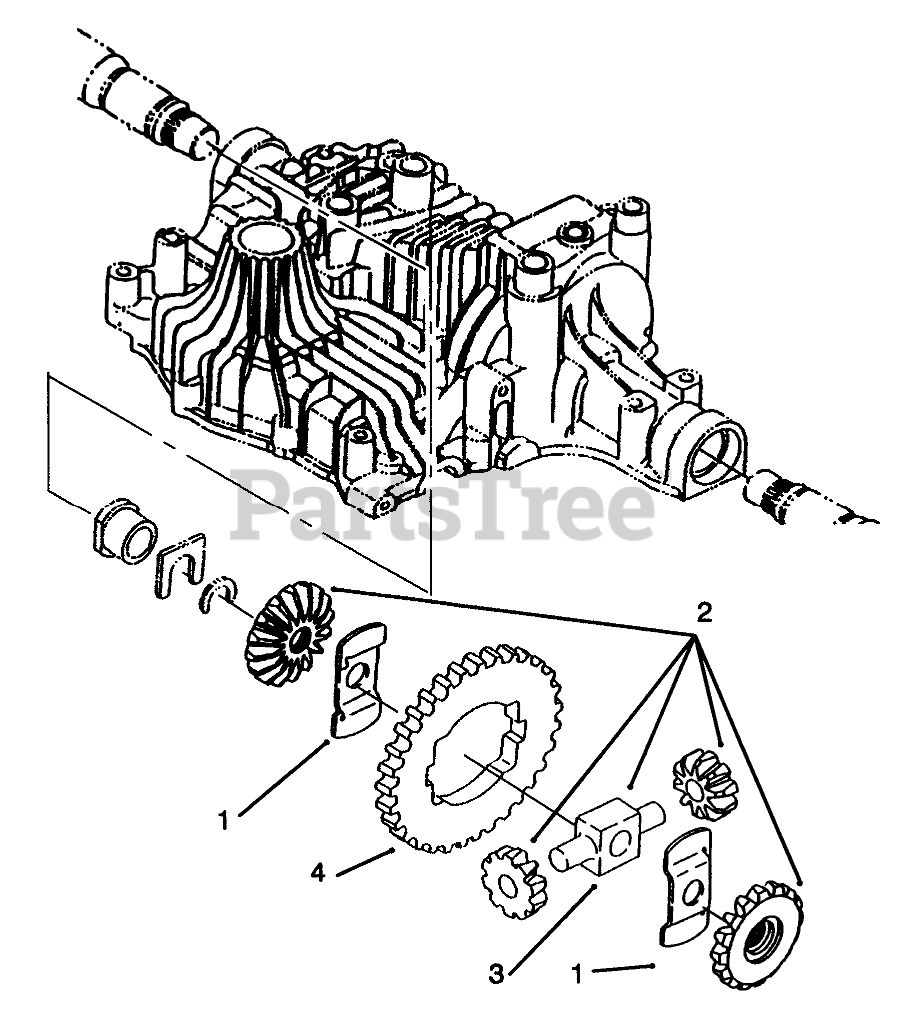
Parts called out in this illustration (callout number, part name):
1	WASHER-THRUST
2	Differential Gear ASM
3	Shaft-Pinion
4	GEAR - FINAL
